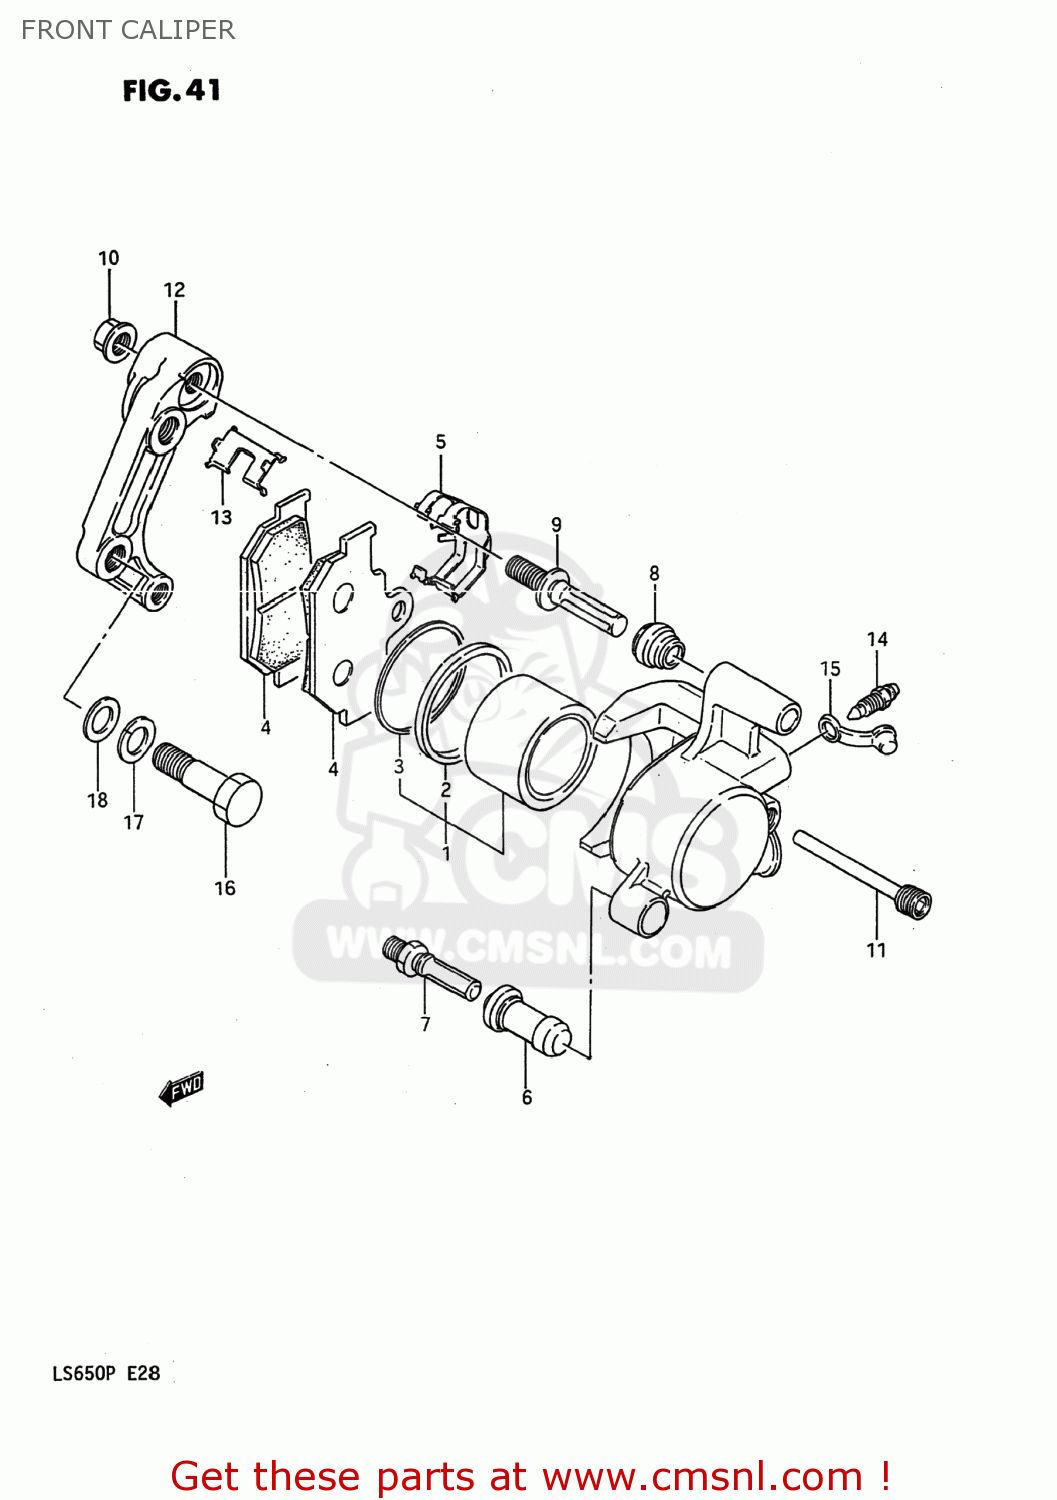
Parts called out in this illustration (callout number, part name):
1	PISTON SET
2	SEAL,PISTON
3	SEAL,DUST
4	PAD
5	SPRING
6	BOOT
7	PIN,BOLT
8	BOOT
9	PIN,SLIDE
10	NUT,SLIDE PIN
11	PIN,HANGER
12	BRACKET
13	RETAINER
14	BLEEDER
15	CAP,BLEEDER
16	BOLT(10X38)
17	WASHER,LOCK,10
18	WASHER
